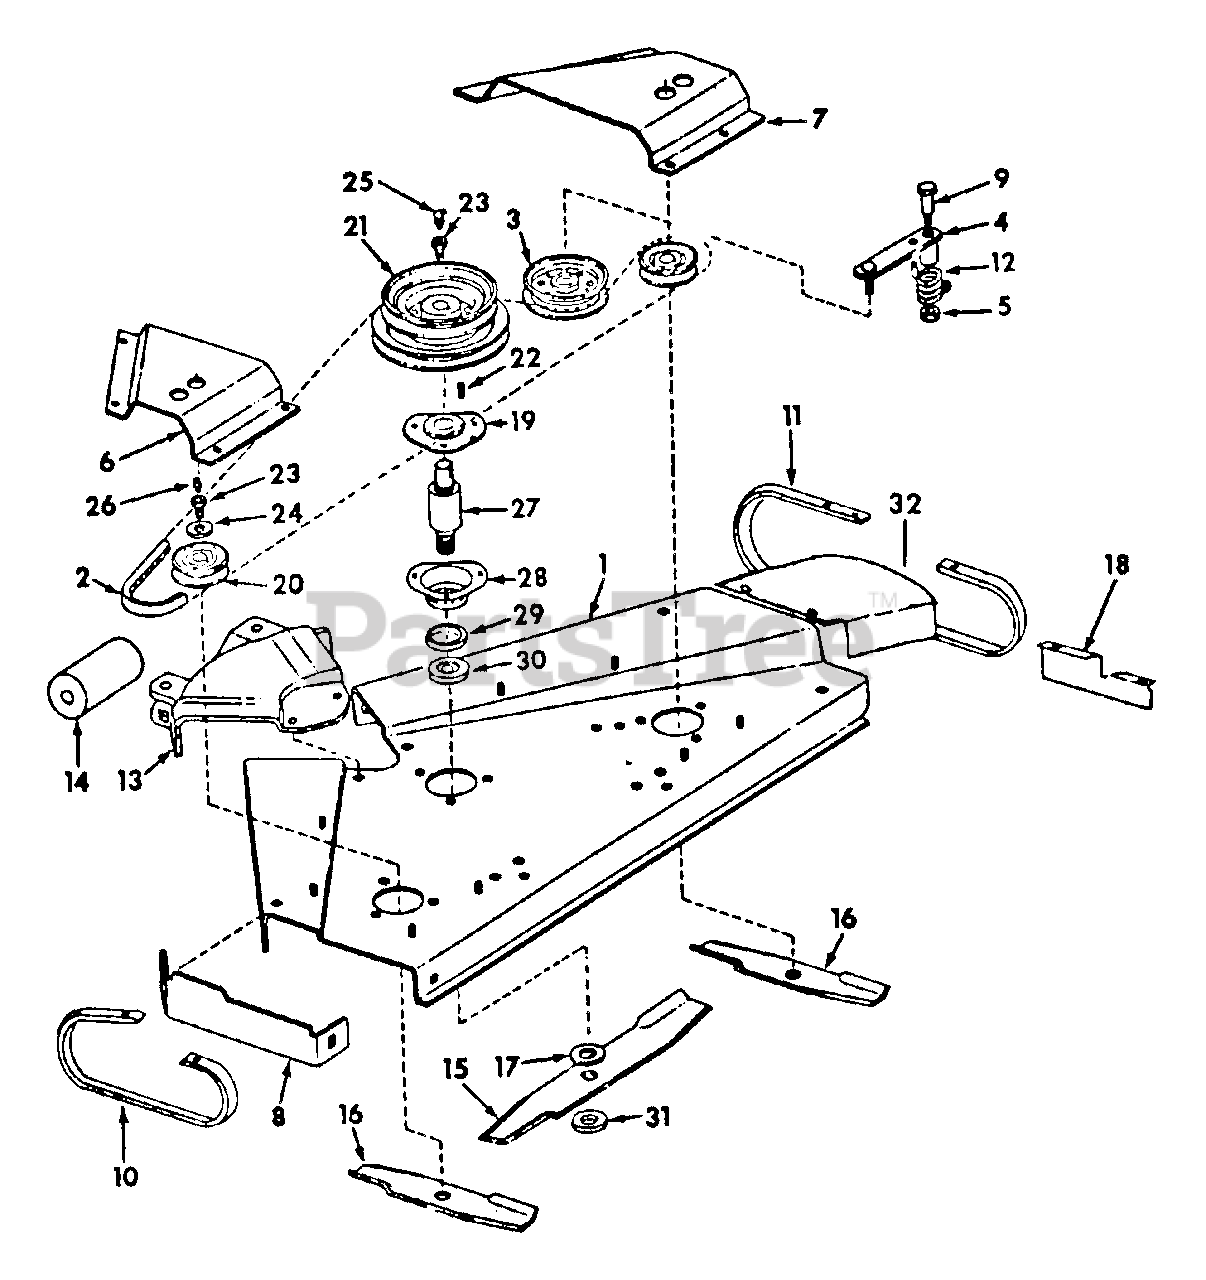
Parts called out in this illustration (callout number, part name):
1	HOUSING ASSY, ROTOR; 38 IN. BLADE.
2	BELT, SPINDLE DRIVE; 38 IN. BLADE.
3	PULLEY, FLAT IDLER
4	ARM ASSY, IDLER
5	NUT, CENTER LOCK
6	SHIELD, BELT LH
7	SHIELD, BELT RH
8	SIDE, HOUSING LH; 38 IN. BLADE.
9	BOLT, IDLER ARM PIVOT
10	RUNNER, MOWER LH
11	RUNNER, MOWER RH
12	SPRING, TORSION
13	HOUSING, CENTER
14	ROLLER, FRONT
15	BLADE, CENTER; 38 IN. BLADE HARD SURFACED
16	BLADE, OUTER; 38 IN. BLADE HARD SURFACED
17	WASHER, BLADE FRICTION
19	CAP, SPINDLE HOUSING
20	PULLEY, OUTER
21	PULLEY, CENTER
22	KEY, 1/4 x 3/4 SQ-PARALLEL
23	BOLT, END
24	WASHER, SPINDLE
25	FITTING, 3/8 DRIVE TYPE 45 DEG ANGLE LUG, END BOLT
26	FITTING, 5/16 DRIVE TYPE STR LUE END BOLT
27	BEARING, BALL STR FITTING
28	HOUSING, SPINDLE
29	CUP, SPINDLE
30	SPACER, BLADE
31	WASHER, 25/32 x 2 x 11 GA BLADE DRIVE DISC SPACING
32	DEFLECTOR, 38 IN.
18494-R1	BOLT, 3/8 X 1 ZND HEX-HD MACH
18684-R1	BOLT, 3/8 x 1-1/4 C-Z SO-NK CRG
18684-R1	BOLT, 3/8 x 1-1/4 C-Z SQ-NK CRG
20914-R1	BOLT, 1/2 x 7-1/2 C-Z SQ-NK CRG
22476-R1	BOLT, 3/8 x 1-1/8 ZND SQ-NK CRG
22476-R1	BOLT, 3/8 x 1-1/8 ZND SQ-W CRG
